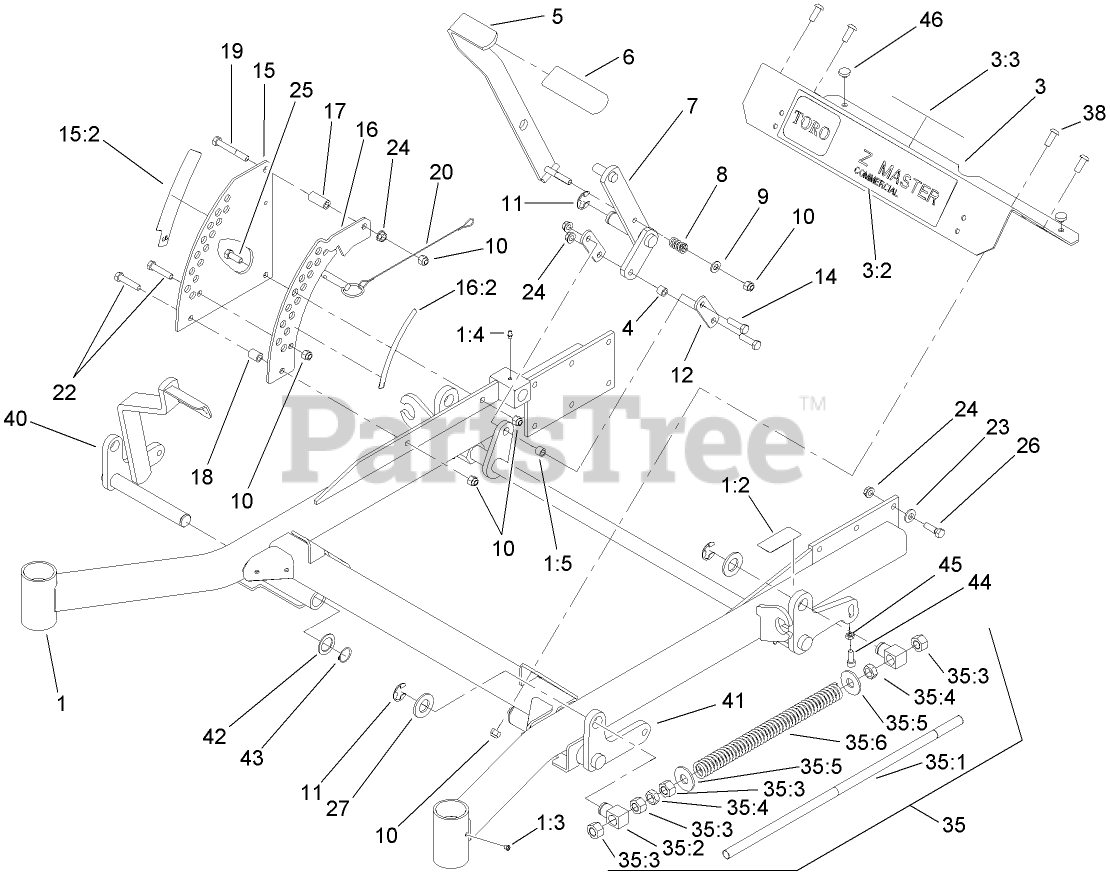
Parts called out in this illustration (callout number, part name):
1	FRONT FRAME ASM
1:2	Decal-Brake, Parking
1:4	FITTING-GREASE
1:5	Bushing
3	FOOTREST
3:3	DECAL-WARNING
4	Bushing
5	LEVER-LIFT
6	GRIP-LEVER, LIFT
7	ARM-LIFT, DECK
8	SPRING-COMPRESSION
9	WASHER-FLAT
10	NUT-LOCK, NI
11	RING-RETAINING, EXT
12	ARM-LIFT, DECK
14	SCREW-HH
15	PLATE-DECK LIFT, OUTER
15:2	Decal-Height, Deck
16	PLATE-DECK LIFT, INNER
16:2	Decal-Height, Deck
17	BUSHING-LEVER, LIFT
18	BUSHING-LEVER, LIFT
19	SCREW-HH
20	Hitch Pin ASM
22	SCREW-HH
23	WASHER-BELLEVILLE
24	NUT-HHF, WHIZ
25	SCREW-HH
26	SCREW-HH
27	WASHER-FLAT
35	Front Frame Spring ASM
35:1	ROD-LIFT, DECK
35:2	SWIVEL-DECK MOUNT, REAR
35:3	NUT-HEX
35:4	NUT-JAM
35:5	WASHER-FLAT
35:6	SPRING-SUPPORT, DECK
38	SCREW-HSBH
40	LIFT-DECK, RH FRONT
41	LIFT-DECK, LH
42	WASHER-SPACER
43	RING-RETAINING
44	SCREW-HSH
45	NUT-JAM
46	BUMPER
